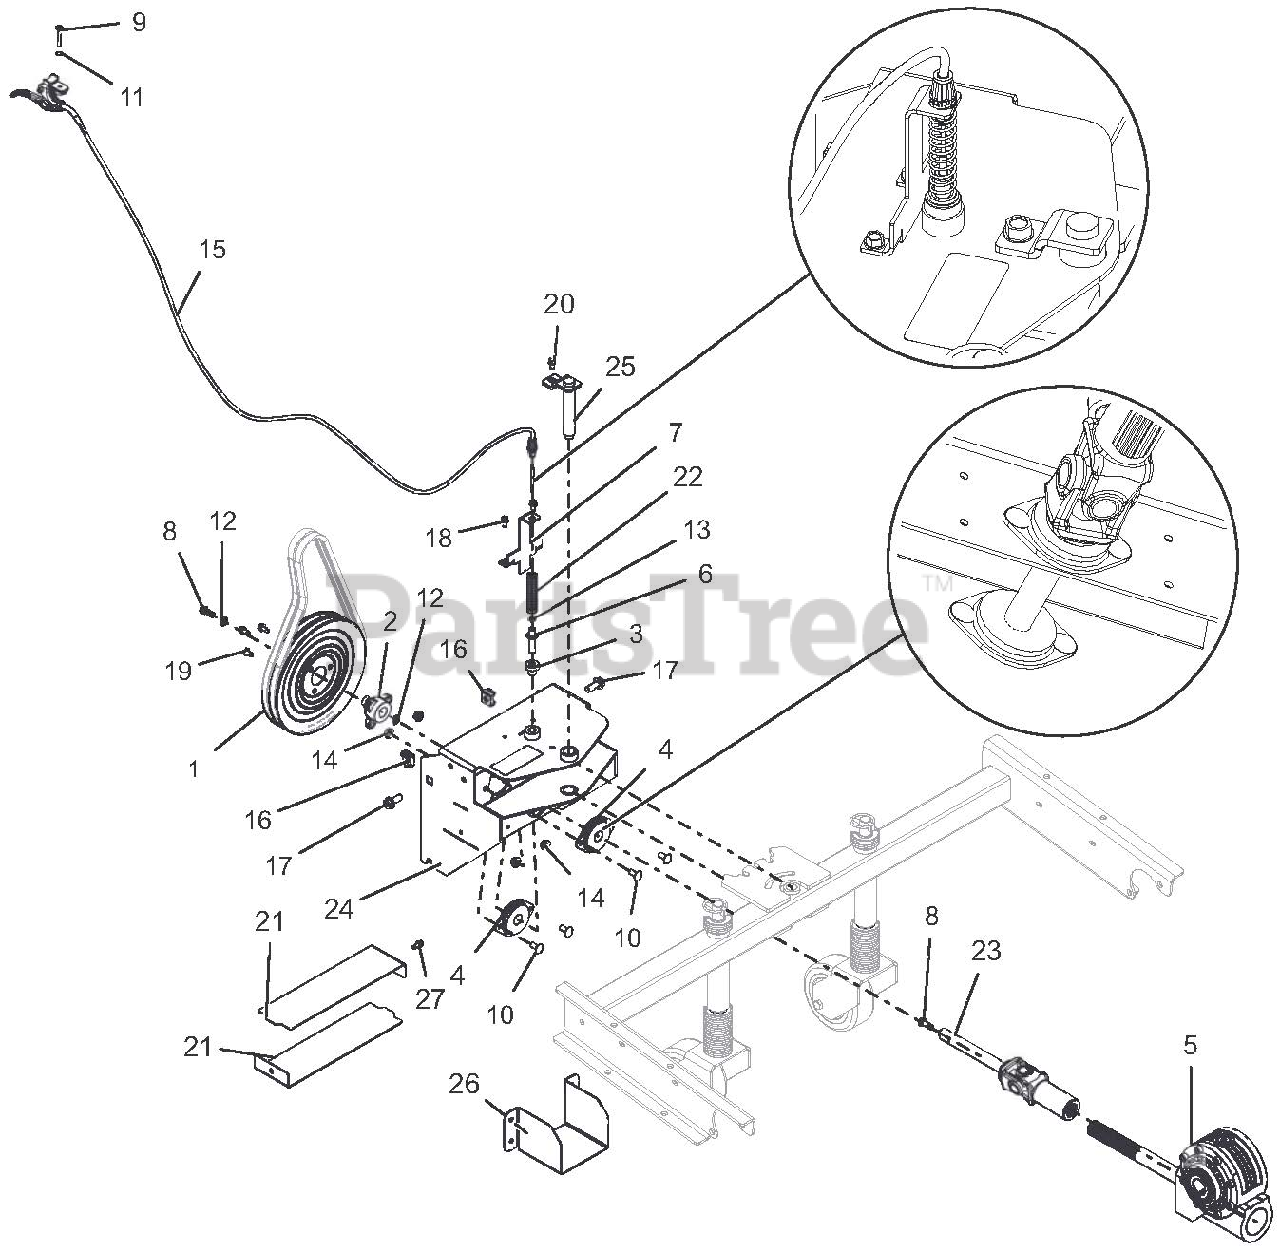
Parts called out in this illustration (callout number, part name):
1	PULLEY, SPIN FORM DUAL GROOVE
2	PULLEY HUB, BOLT-ON D-BORE .75
3	SPACER -FLANGED .390X.500X.781
4	BEARING, 2 BOLT FLANGE -.75 ID
5	GEARBOX, WORM - 8.25:1
6	PIN, ADJUSTABLE ANGLE BRUSH
7	BRKT, PIN HOLDER
8	BLT-HEX .31-24X.75 YWZC GR5
9	SCR-MCH .25-20X1.50 OVAL HD
10	@BLT-RDHDSQNK .31-18X.75 G5YZ
11	WSHR-LK-INT .250 TH TYA
12	WSHR-LK .312X.097 HVY YWZC
13	@NUT-HEX 10-24 YWZC
14	@NUT-LK-TOP-FLG .31-18 YWZC
15	CABLE, REMOTE BRUSH LOCK
16	NUT-RETNR .38-16 TINRMAN
17	BLT-SERHFWH .375-16X1.0 YWZC
18	SCR-TAP .25-20X.50 HWH TR YWZ
19	SCR-TAP .25-20X.50 HWH TR YWZ
20	SCR-TAP .25-20X.50 HWH TR YWZ
21	GUARD, BRUSH PTO
22	SPRING, COMPRESSION
23	DRIVELINE, SERIES 07 (U-JOINT)
24	ADAPTER, BRUSH
25	WLDMT, BRUSH PIN
26	GUARD, BRUSH U-JOINT
27	SCR-TAP .25-20X.50 HWH TR YWZ
